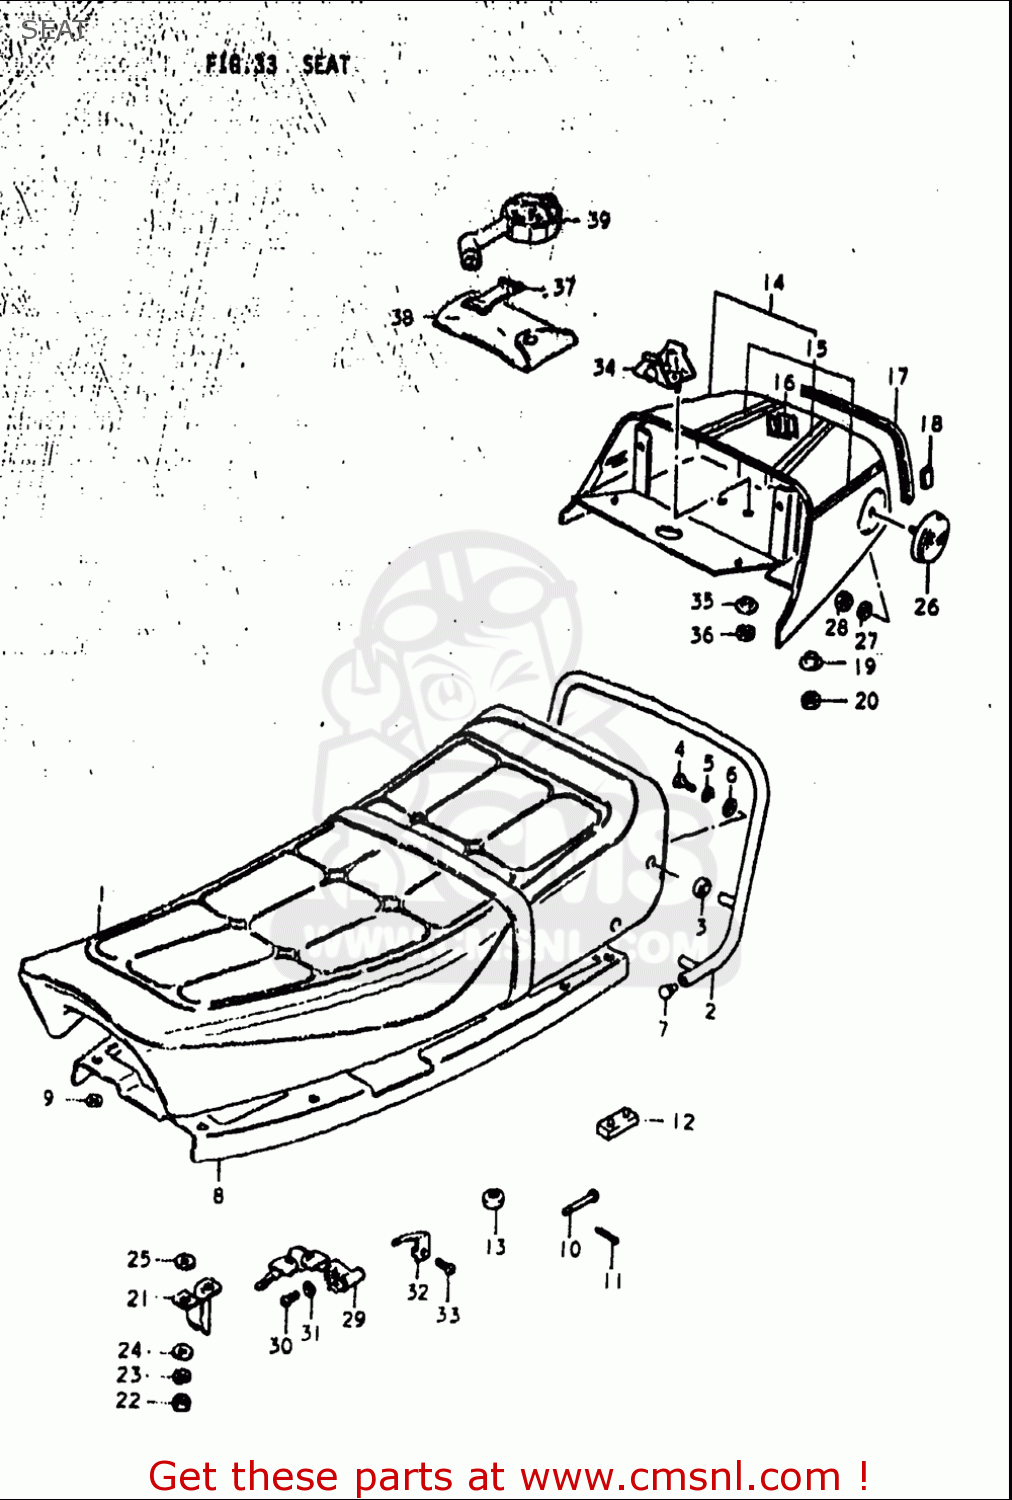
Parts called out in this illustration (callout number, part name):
3	CUSHION
4	BOLT
5	WASHER,LOCK
6	WASHER
7	END,SHEET HANDLE
9	NUT
10	PIN
11	PIN
12	CUSHION
13	CUSHION
18	CLIP,SEAT TAIL COVER M
19	WASHER
20	NUT 6MM
21	STRIKER,SEAT LOCK
22	NUT
23	WASHER,LOCK
24	WASHER
25	WASHER(6.5X20X1.2)
26	REFLEX REFLECTOR,RR
27	WASHER
28	NUT
29	LOCK ASSY,SEAT
30	SCREW
31	WASHER,LOCK
33	SCREW
35	WASHER
36	NUT
37	BAND
38	TOOL ASSY
